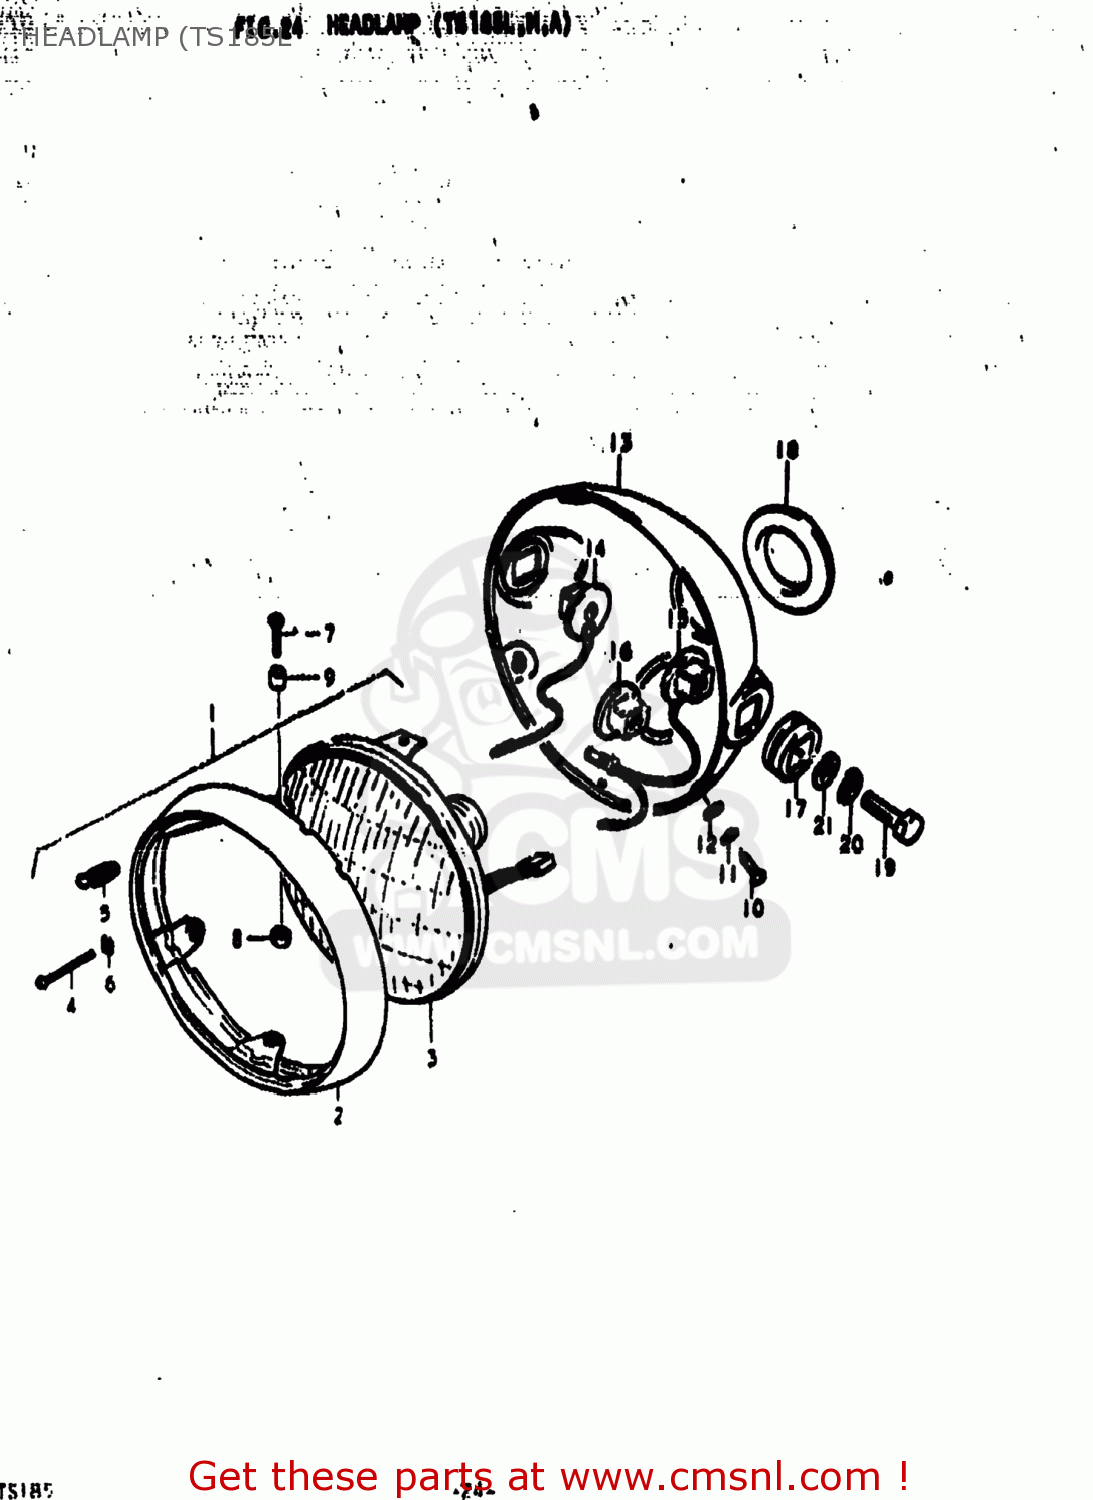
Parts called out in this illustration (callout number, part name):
1	HEADLAMP ASSEMBLY
2	RIM,HEADLAMP
3	LAMP UNIT
4	SCREW,HEADLAMP ADJUST
5	SPRING,HEADLAMP ADJUST
6	NUT,HEADLAMP ADJUSTER
7	SCREW
8	NUT,ADJUSTING
9	SPACER,HEADLAMP UNIT
10	SCREW
11	LOCK WASHER
12	WASHER
13	HOUSING COMP,HEADLAMP
14	SPACER,HEADLAMP HOUSING
15	SPACER,HEADLAMP HOUSING
16	SPACER,HEADLAMP HOUSING
17	CUSHION,HEADLAMP HOUSING
18	GROMMET,HEADLAMP HOUSING
19	BOLT
20	LOCK WASHER
21	WASHER
